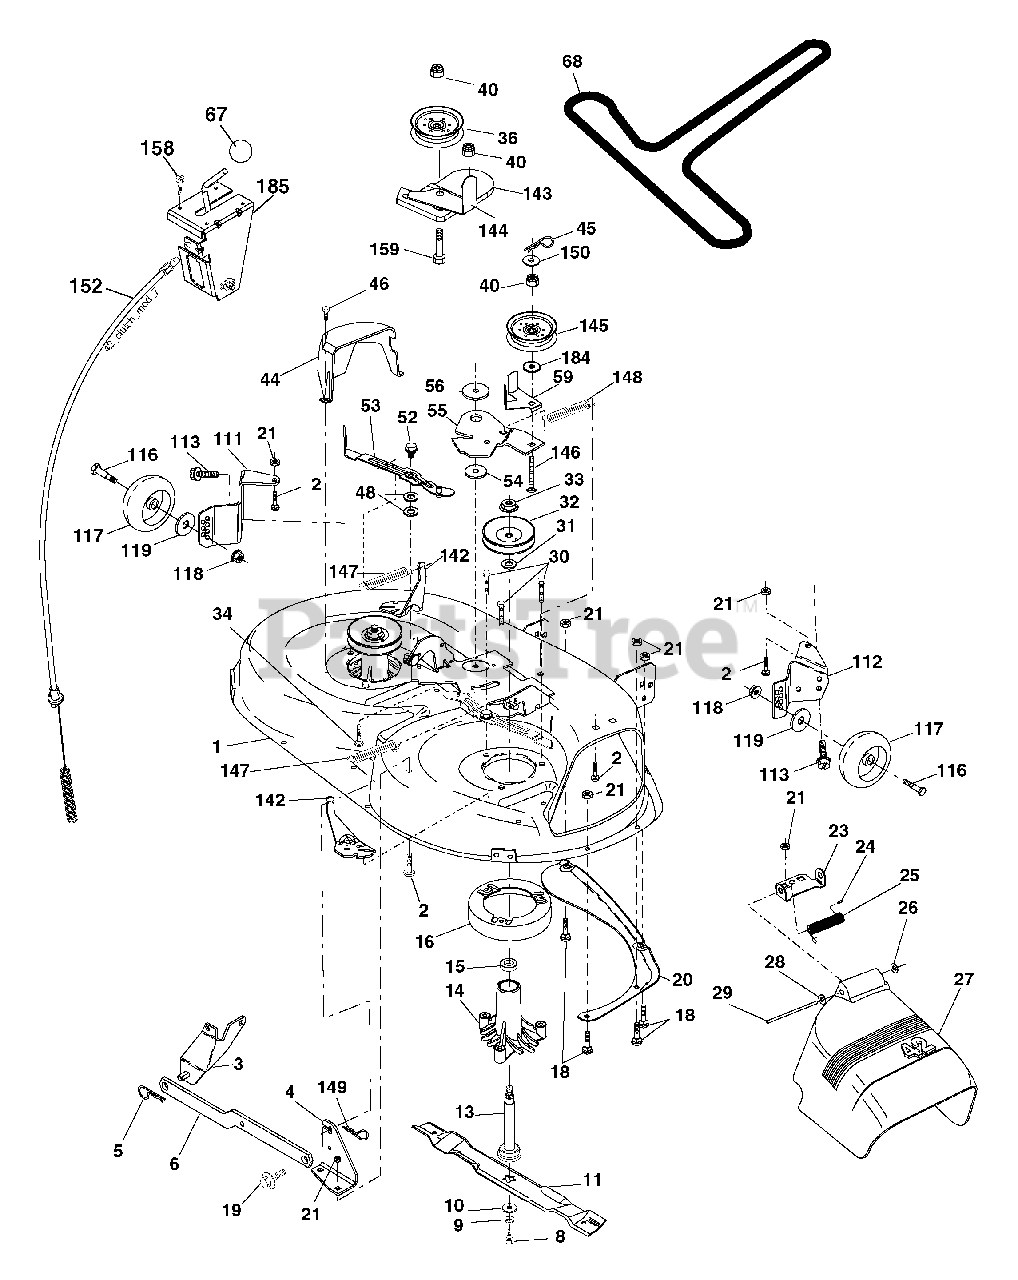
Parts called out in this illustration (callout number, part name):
1	Mower Deck Assembly, 42"
2	Bolt
3	Bracket Asm Fr. Sway Bar 3/42
4	Bracket Asm Deck 42" Sway Bar
5	Retainer Spring
6	Bar Sway Deck
8	Bolt 3/8-24 x 1.25 Gr. 8 patched
9	Washer, Lock
10	Washer, Hardened (The following Blades are available)
11	Blade Mower 42" Hi-Lift
13	Shaft Assembly, Mandrel, Vented
14	Housing, Mandrel, Vented
15	Bearing, Ball, Mandrel
16	Stripper, Mandrel Deck
18	Bolt, Carriage 5/16-18 x 5/8
19	Bolt, Shoulder
20	Baffle, Vortex
21	Nut
23	Bracket, Deflector Mower 42"
24	Cap, Sleeve 80 x 112 Blk Mower
25	Spring, Torsion, Deflector 2 52
26	Nut, Push Phos & Oil
27	Shield, Defl ector 42" Blk
28	Washer 11/32 x 5/8 x 16 Ga.
29	Rod, Hinge 42" 6 75 W/G
30	Screw Thdrol
31	Washer, Spacer Mower Vented
32	Pulley, Mandrel
33	Nut, Toplock
34	Bolt Carr SH 3/8-16 x 1-1/2 Gr.5
36	Pulley, Idler, Flat
40	Nut Lock 3/8-16
44	Guard, Mandrel, LH
45	Retainer
46	Screw, Thdrol 1/4-20 x 5/8 T
48	Washer, Hardened
52	Bolt, Shoulder 5/16-18 unc
53	Arm Assembly, Pad, Brake
54	Washer, Hardened
55	Arm, Idler
56	Spacer, Retainer
59	Guard TUV Idler
67	Knob Round
68	V-Belt, 42" Mower
111	Bracket Asm. Whl Ga. LH
112	Bracket Asm Whl Ga. RH
113	Screw 5/16-18
116	Bolt, Shoulder
117	Wheel, Gauge
118	Nut Centerlock 3/8-16
119	Washer 3/8 x 7/8 x 14 Ga.
142	Arm Spring Brake Mower
143	Bracket Arm Idler 42"
144	Keeper Belt 42" Clutch Cable
145	Pulley Idler Flat
146	Bolt Carriage Idler
147	Spring Extension
148	Spring Return Idler
149	Retainer Spring Yellow
150	Washer 9/32 x 3/4 x 10 Ga.
152	Clutch Cable 42"
158	Screw Hex Thd Cut 1/4-20 x 1/2
159	Bolt Rdhd Sqn 3/8-16 unc x 1-3/4
184	Washer 13/32 x 7/8 x 10 Ga.
185	Head Asm Cable Clutch
